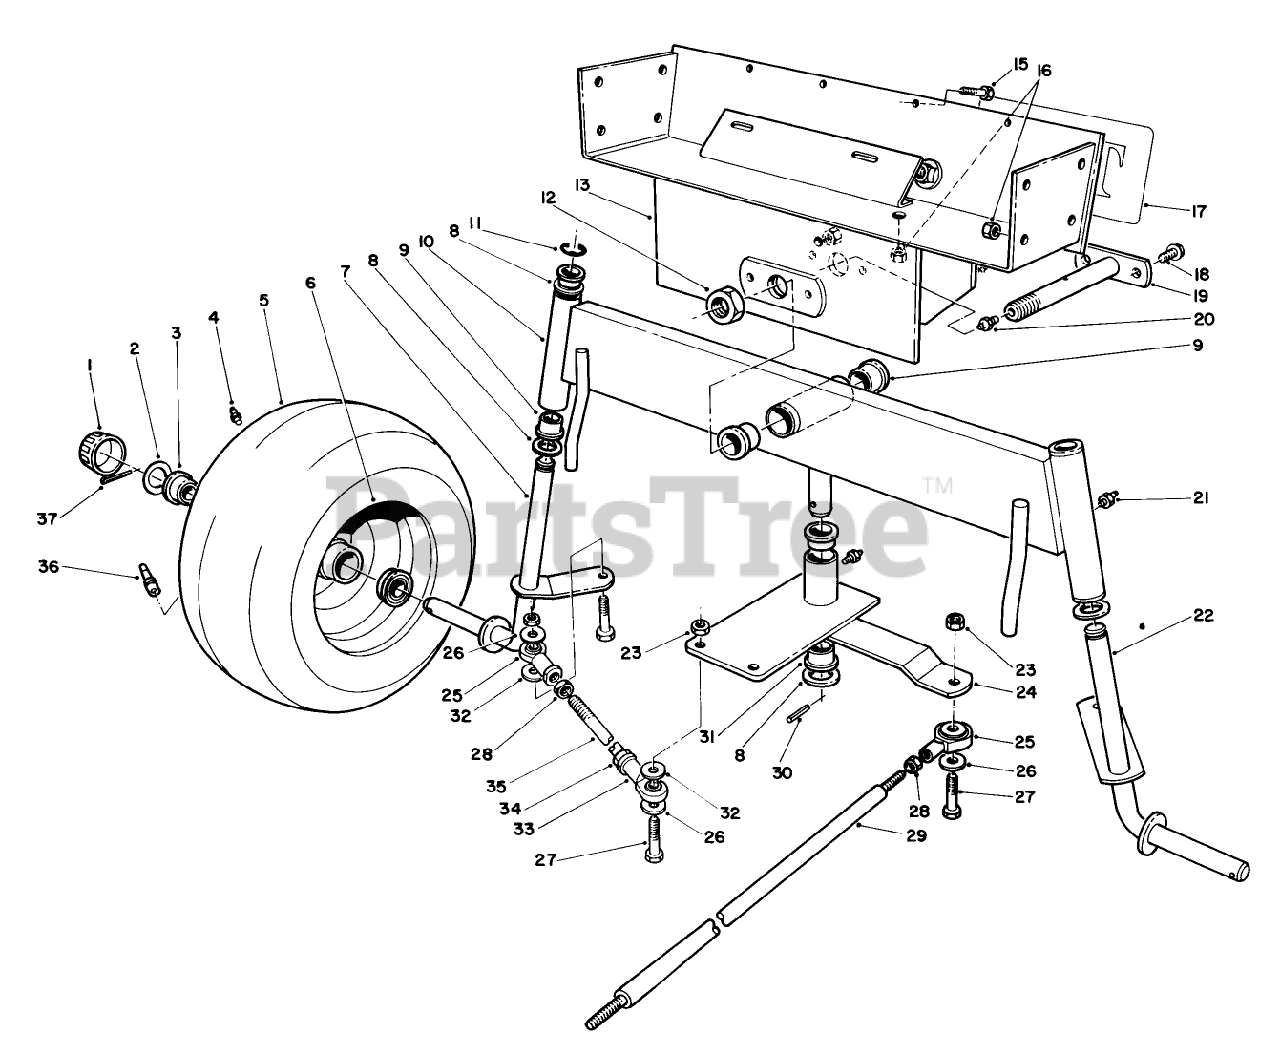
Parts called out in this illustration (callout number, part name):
1	Cap-Hub
2	WASHER-PLAIN
3	Bearing
4	FITTING-GREASE
5	Tire
6	FRONT WHEEL
7	Spindle R.H.
8	WASHER-THRUST
9	BUSHING PM
10	Rear Axle (Incl. Ref. #9 & 20)
11	E-RING
12	NUT-LOCK NI
13	Frame-Rear
15	SCREW-HH
16	NUT-LOCK, NI
17	Decal
18	SCREW-HHFTF
19	Axle-Pivot
20	FITTING-GREASE
21	GREASE FITTING
22	Spindle LH.
23	NUT-HEX
24	Pivot Plate (Incl. Ref. #20 & 30)
25	BALL JOINT RH
26	WASHER-FLAT
27	SCREW-HH
28	NUT-JAM
29	Rod-Steering
30	PIN-SPRING
31	BEARING-FLANGE
32	WASHER
33	BALL JOINT LH
35	TIE ROD - STEERING
36	STEM-VALVE
37	PIN-COTTER
